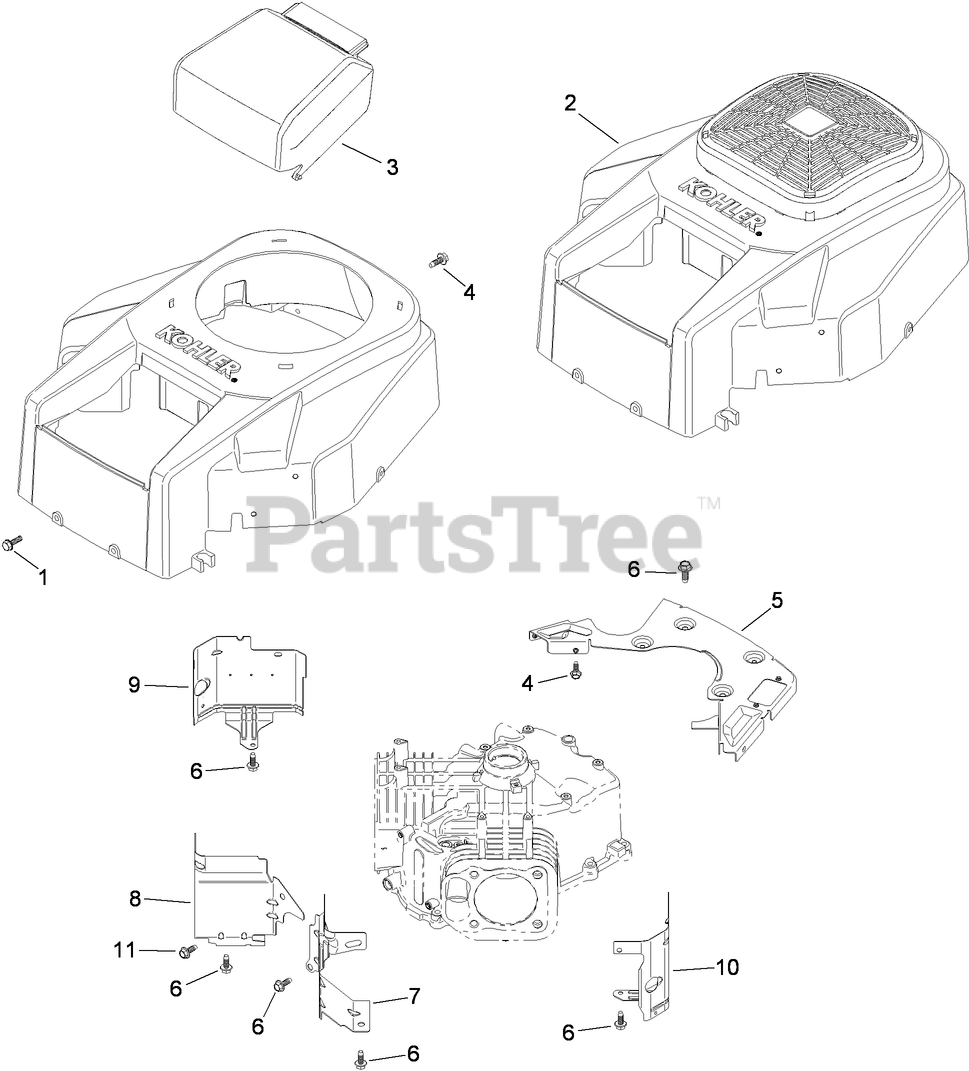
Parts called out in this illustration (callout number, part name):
1	SCREW-TAP (M6X1.7X18)
2	BLOWER HOUSING ASM (FIXED GUARD) (INCLUDES 2, 3)
3	COVER-CLEANER, AIR (BLACK)
4	SCREW-FLANGE, THREAD FORMING (M5X0.8X16)
5	PLATE-BACKING
6	SCREW-FLANGE, THREAD FORMING (M6X1.0X16)
7	BAFFLE-VALLEY (No.2 SIDE)
8	BAFFLE-VALLEY (No.1 SIDE)
9	BAFFLE-BARREL, CYLINDER (No.1 SIDE)
10	BAFFLE-BARREL, CYLINDER (No.2 SIDE)
11	SCREW-HHFTF (M5X.80X10)
